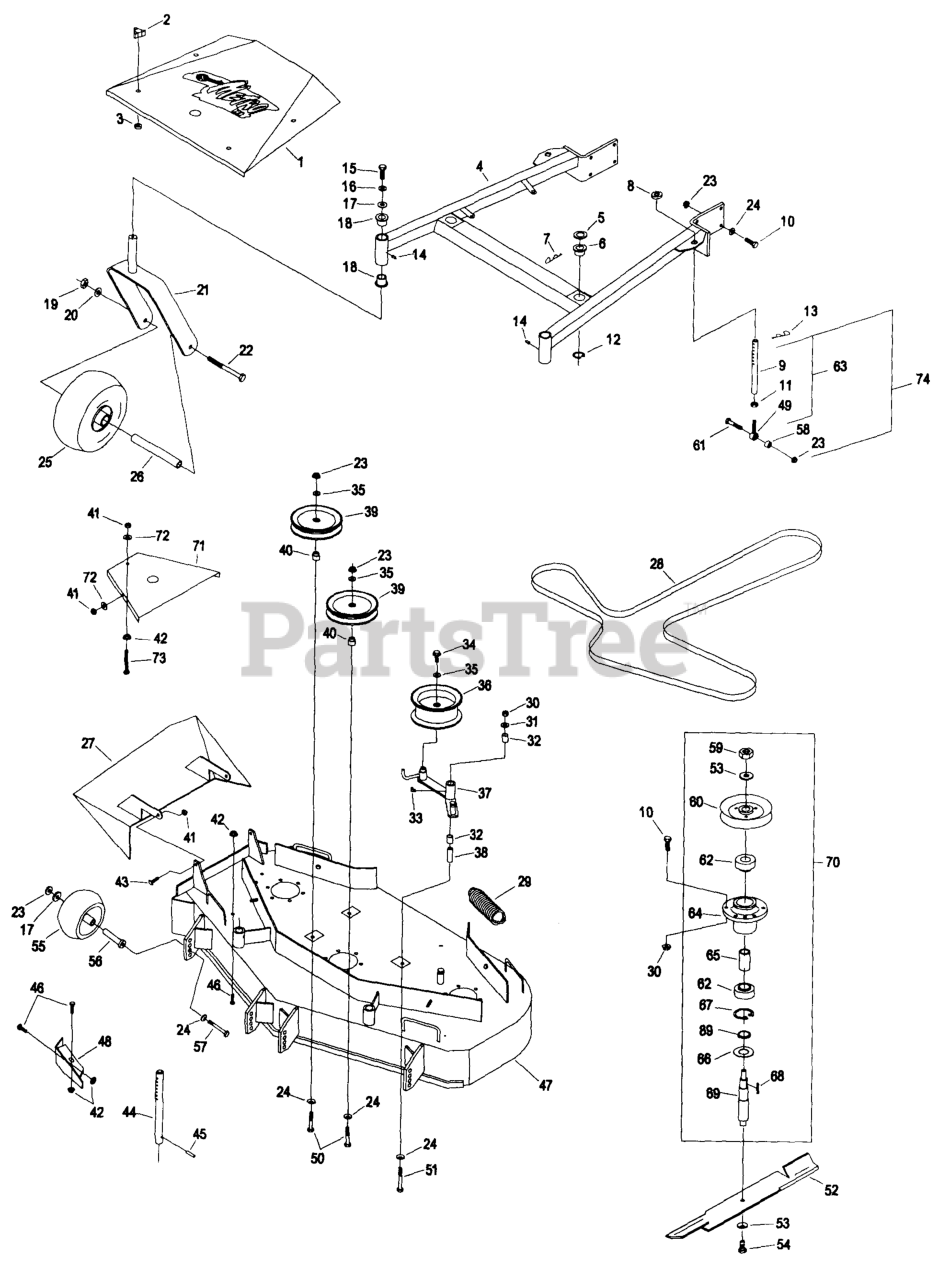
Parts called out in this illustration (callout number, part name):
1	SHIELD W/DECAL,MHP48
2	KNOB-3 PRONG
4	DECK SUPPORT W/BSHGS 48"
5	SPACER-DECK SUPPORT
6	BUSHING-DECK
9	LINK, DECK SUPPORT
13	PIN,HAIR COTTER
18	BEARING-FLANGED
28	BELT - V, B
32	SLEEVE-BEARING
38	BUSHING-PIVOT, IDLER
39	PULLEY-IDLER
40	BUSHING-IDLER
44	ROD,DECK SUPPORT
47	ASM,DECK W/DECALS TTHP/MH
49	BALLJOINT
51	SCREW-HH
53	WASHER-SPRING
55	ROLLER-SCALP, ANTI
56	BUSHING-ROLLER
60	SHEAVE,W/HUB 5.72
62	BEARING
65	SPACER-BEARING
66	GUARD-BEARING, BOTTOM
68	KEY-RECTANGLE
69	SHAFT,SPINDLE
70	HOUSING,CUTTER COMPLETE
73	BOLT,TAP HH
75	SPACER-PULLEY/BEARING
